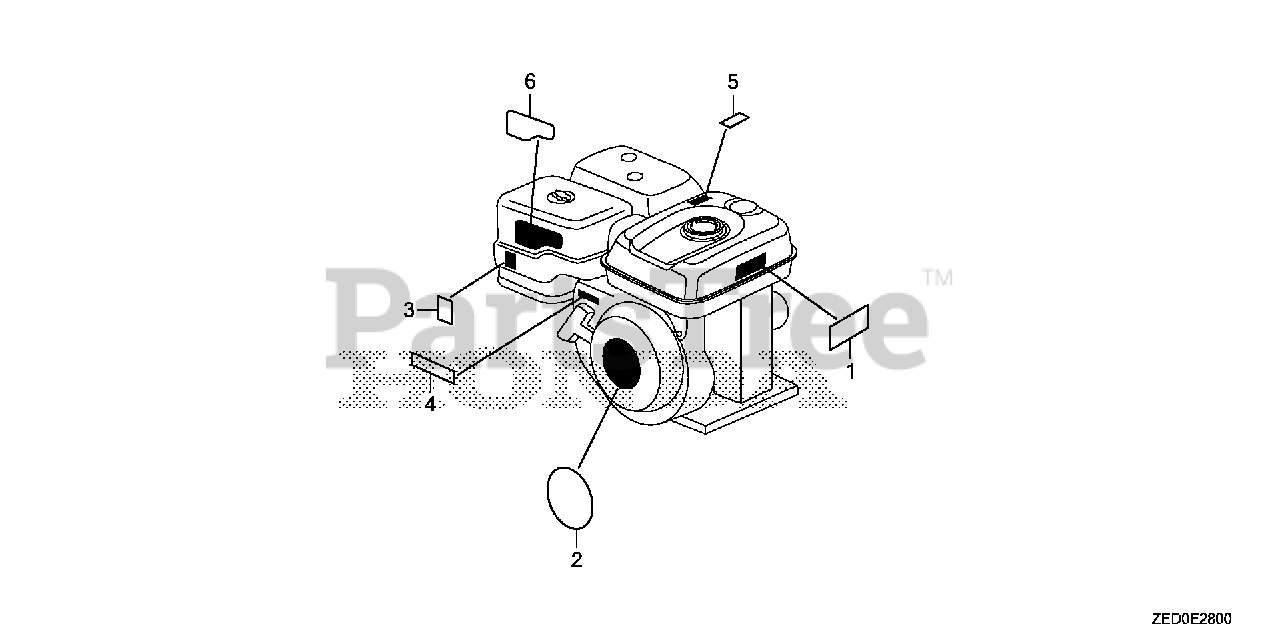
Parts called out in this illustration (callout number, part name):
1	MARK, OPERATOR CAUTION (ENGLISH)
2	EMBLEM (GX160)
3	MARK, CHOKE
4	MARK, THROTTLE INDICATION
5	MARK, EX. CAUTION (ENGLISH)
